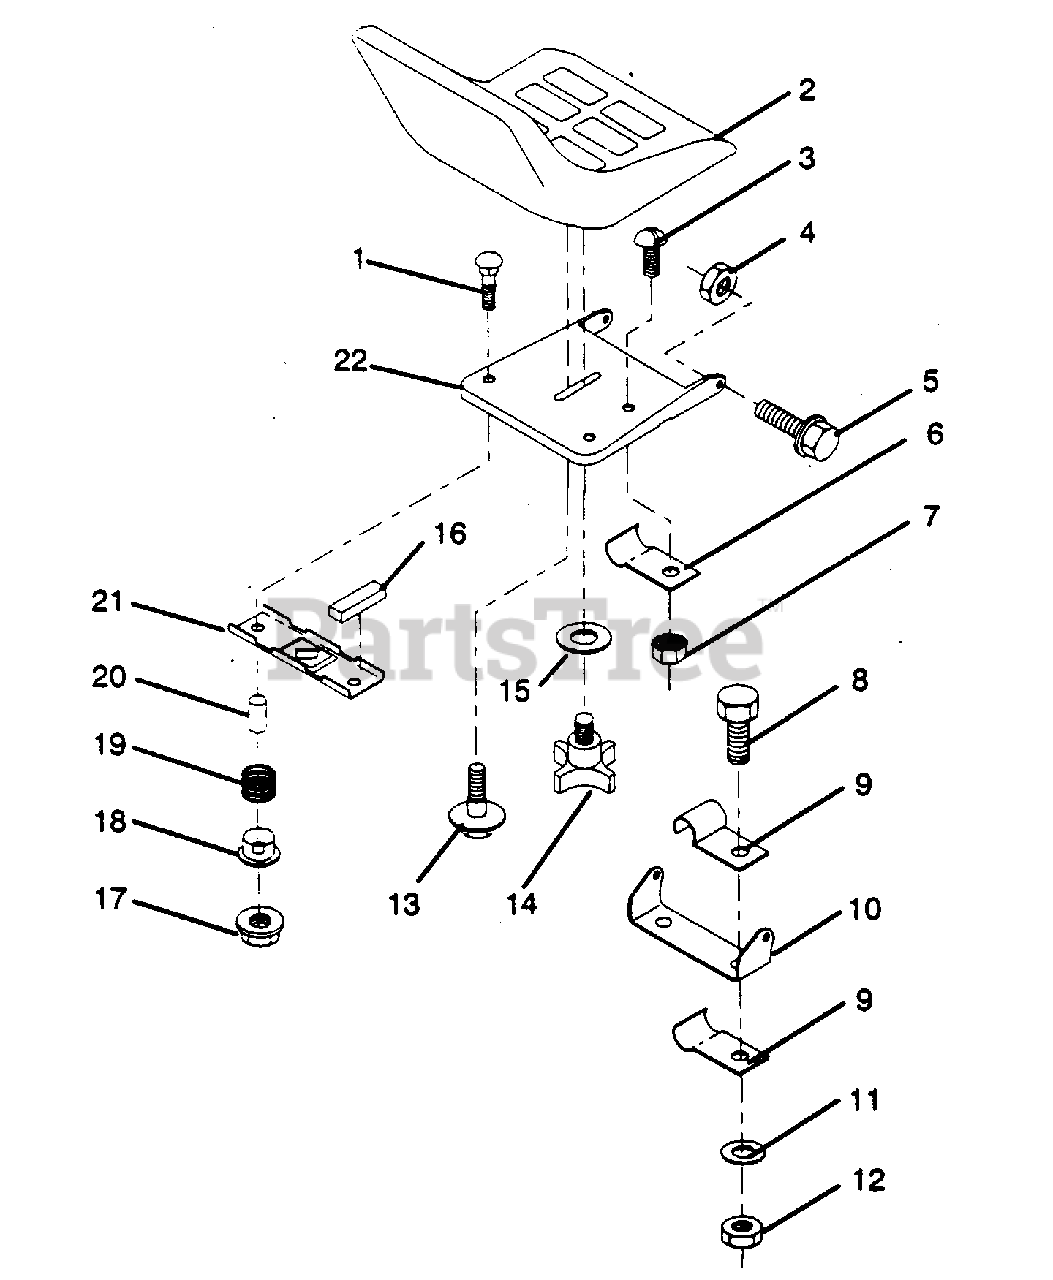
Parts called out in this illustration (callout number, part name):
1	Bolt, Carriage 1/4-20 x 1-1/4
2	Seat
3	Screw, Slotted Pan Head #10-32 x 1/2
4	Nut, Crownlock 5/16-18
5	Bolt, Shoulder 5/16-18 UNC
6	Clip, Insulated
7	Nut, Keps #10-32 UNF
8	Bolt, Fin. Hex 3/8-16 UNC x 3/4
9	Clip, Insulated
10	Bracket, Pivot, Seat
11	Washer 13/32 x 3/4 x 10 Ga.
12	Nut, Crownlock 3/8-16 UNC
13	Bolt, Shoulder
14	Knob, Seat 1/2"
15	Washer 17/32 x 1-3/16 x 12 Ga.
17	Nut, Hex, Large, Flange Lock
18	Bushing, Snap
19	Spring, Compression
20	Spacer, Split 28 ld. x .88 Large
21	Bracket, Switch, Mounting
